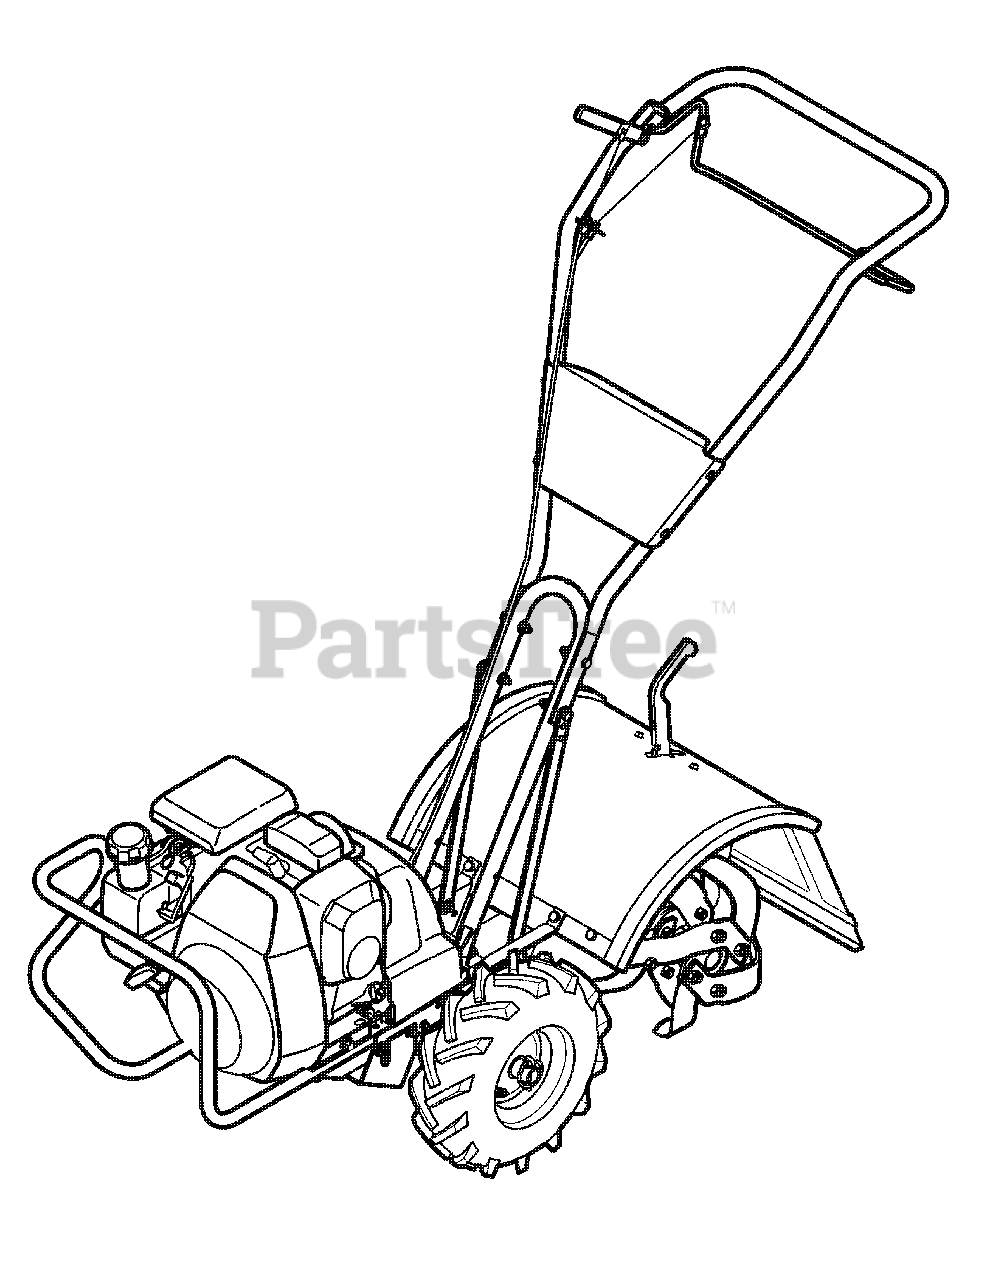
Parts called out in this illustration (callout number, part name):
NA	Pre Filter
NA	Tines-Inner
NA	Rim
NA	Tire
NA	Foam Grip
NA	Handle Knob
